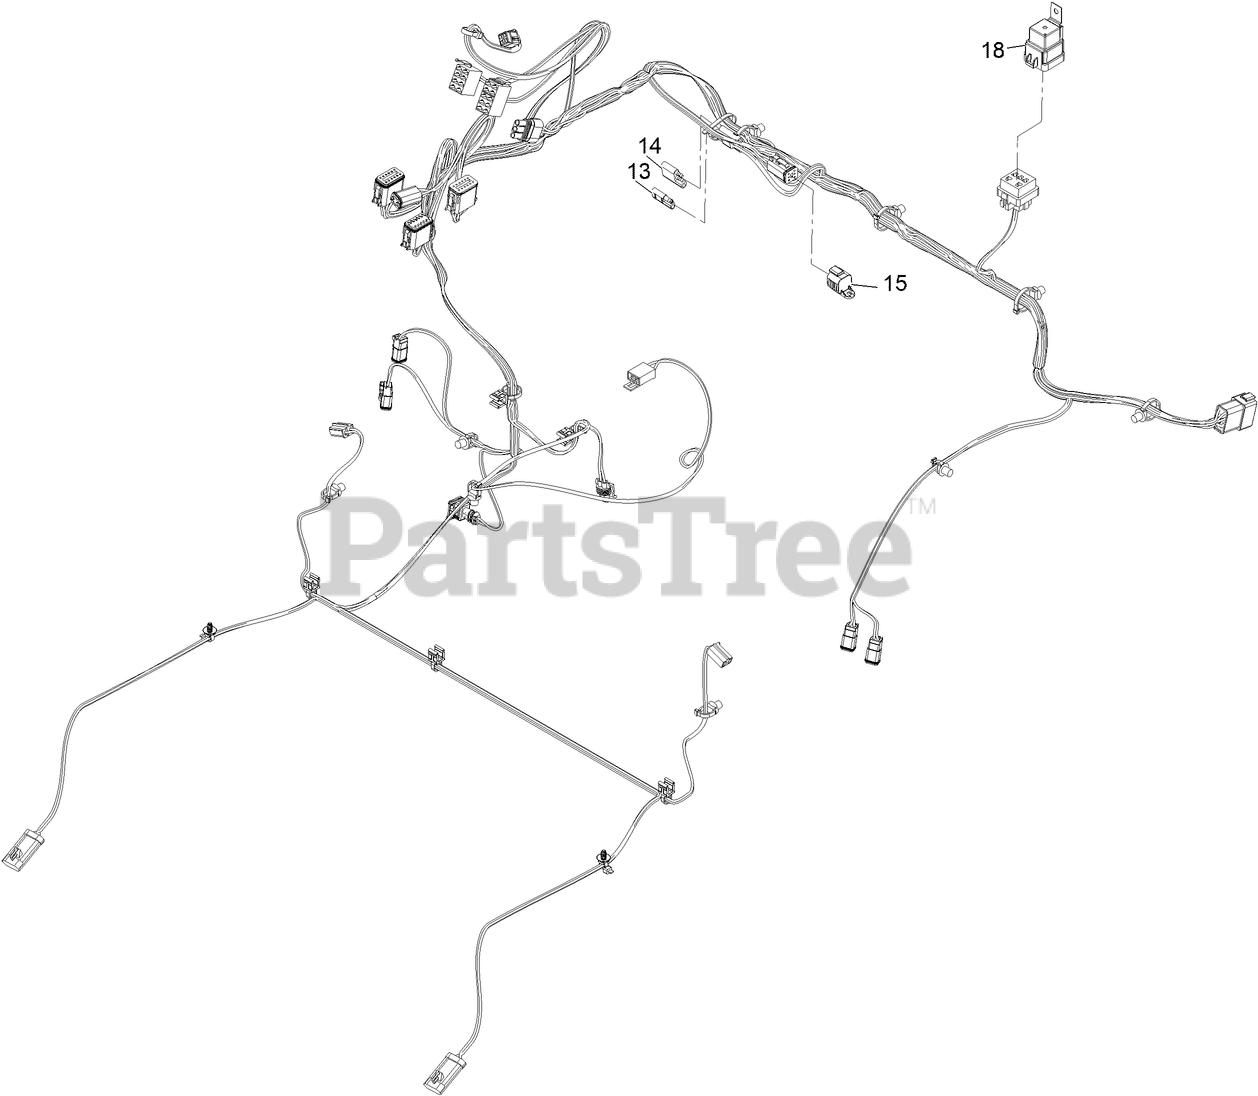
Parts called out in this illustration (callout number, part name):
13	CAP-PLUG
14	CAP-PLUG
15	CAP-PLUG, 6 WAY
18	RELAY-MINI
